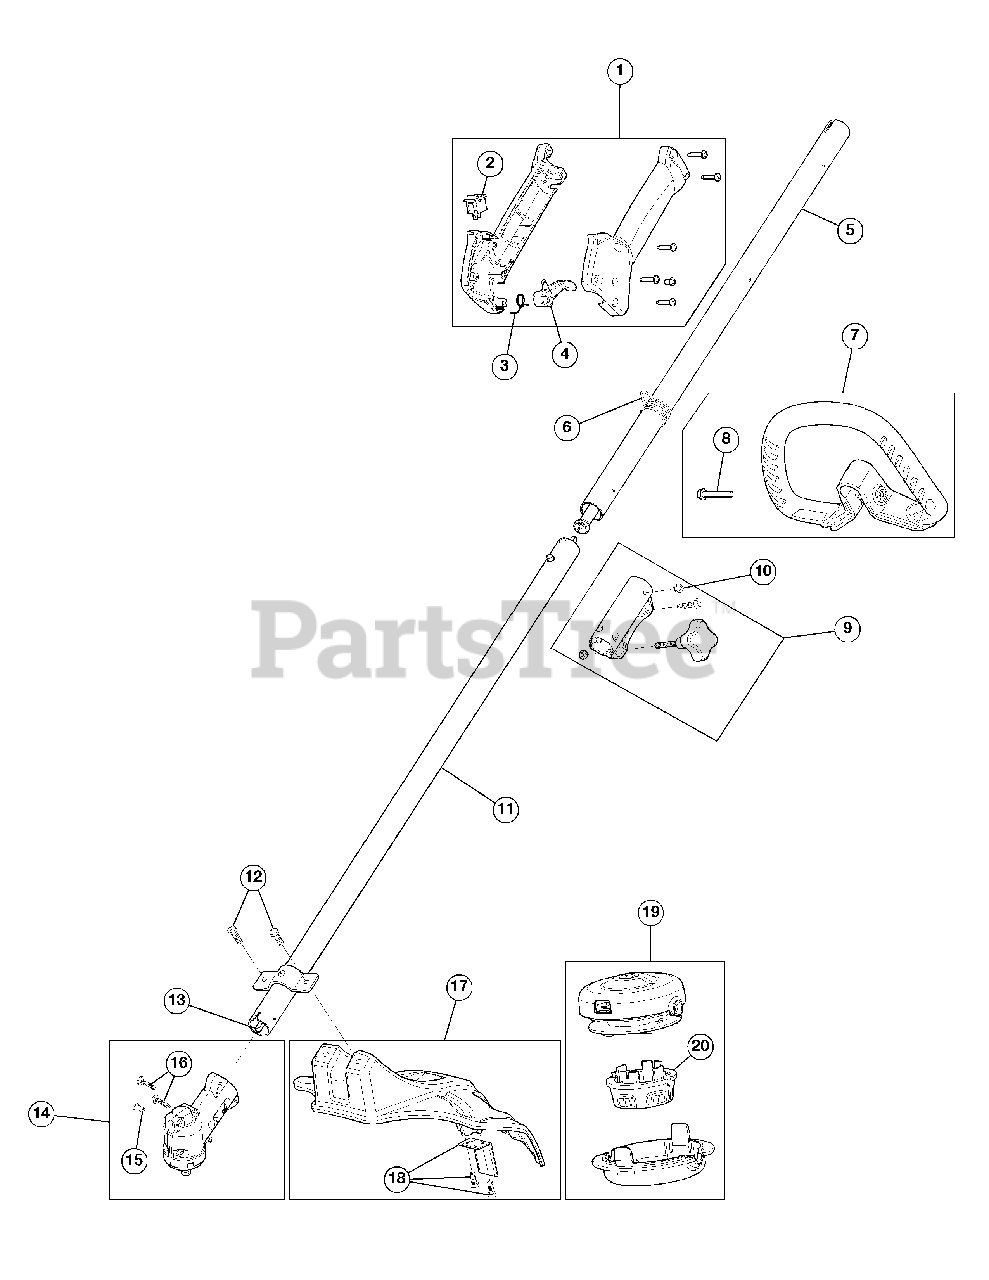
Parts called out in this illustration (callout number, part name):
1	Throttle Housing Assembly (Incl. 2 - 4)
2	Switch Assembly
3	Throttle Trigger Spring
4	Throttle Trigger
5	Upper Drive Shaft Assembly
6	Shoulder Strap Clip
7	D-Handle Assembly (Incl. 8)
9	Split Boom Coupler (Incl. 10)
10	Coupler Anti-Rotation Screw
11	Lower Drive Shaft Housing
12	Shield Mounting Screws
13	Lower Flexible Drive Shaft
14	Gearbox Assembly (Incl. 15 and 16)
15	Anti-Rotation Screw
16	Gearbox Mounting Hardware
17	Shield Assembly (Incl. 18)
18	Blade Assembly
19	Cutting Head Assembly (Incl. 20)
20	Bump Knob
